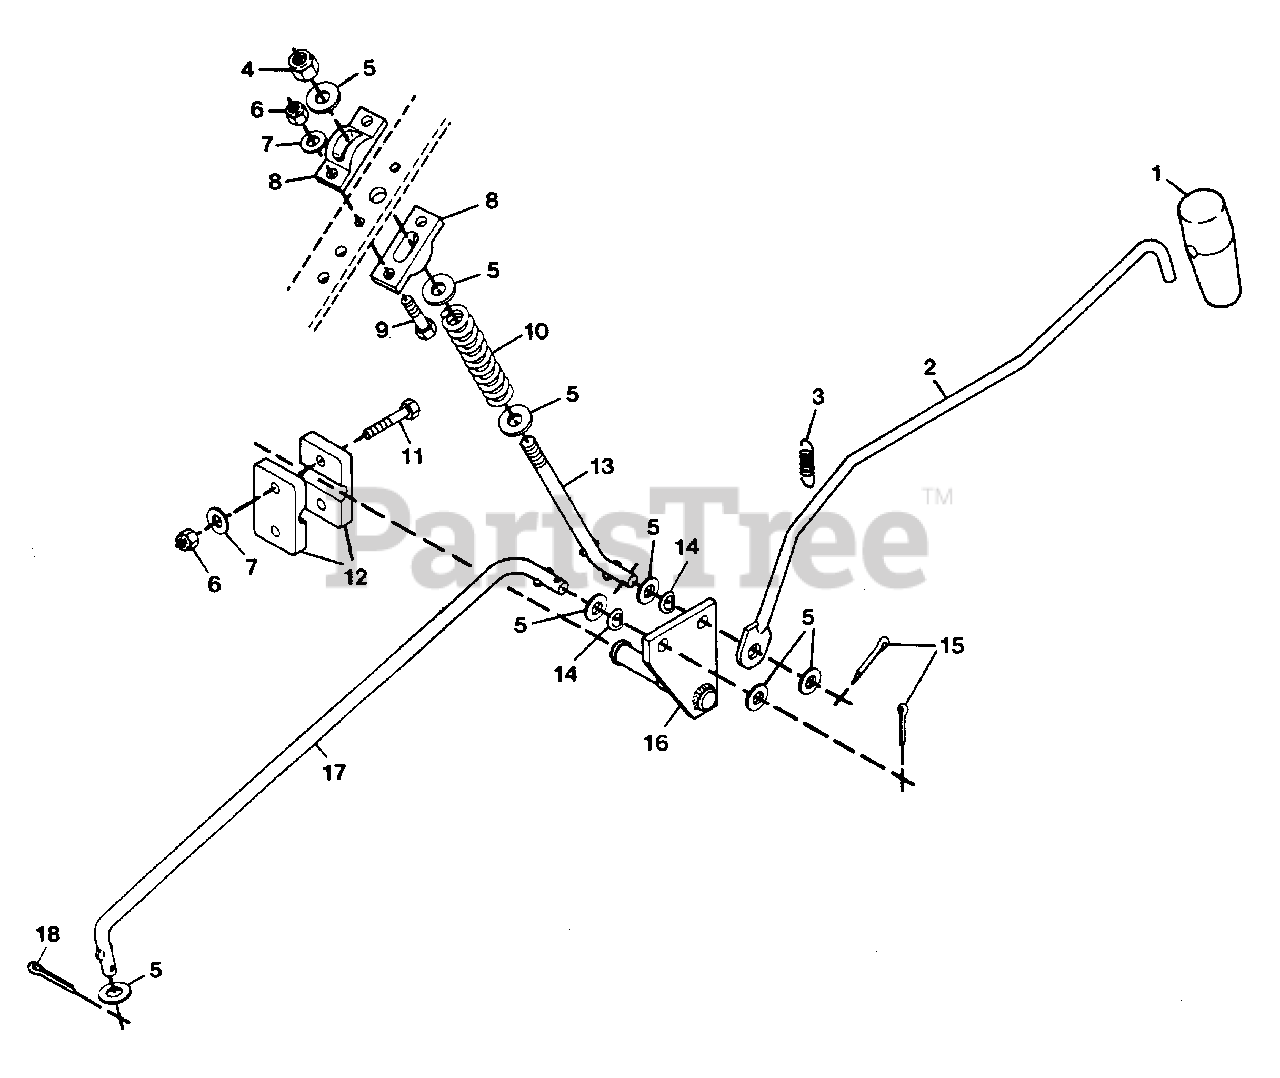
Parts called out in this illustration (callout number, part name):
1	NUT, HEX 3/4-10 LIGHT THIN
2	WASHER, FLAT .812X1.469X.134
3	SPACER
4	SCREW, SET 7/16-14X1.00 SQHCP
5	HUB, WHEEL
6	SPACER
7	BOLT, HEX 3/8-16X.750
8	PLATE, END
9	BEARING, BALL 1.000X2.000X.562
10	RING, RETAINING 2.000 BORE
11	BOLT, STATIONARY CLUTCH
12	PIVOT, STATIONARY
13	PIN, CLUTCH SLIDING
14	O-RING, .438X.625X.094
15	BOLT, HEX 1/2-13X1
16	WASHER, LOCK 1/2 REG.
17	WASHER, OIL STRAINER NUT
18	HOUSING, AXLE 2-SPEED
19	NUT, LOCK 5/16-18
20	WASHER, FLAT .344X.688X.065
21	BUSHING, NYLON .375X.503X.875
22	NUT, LOCK 1/4-20
23	WASHER, FLAT .281X.625X.065
24	WASHER, FLAT .406X.812X.065
25	WELDMENT, ARM SHIFTER
26	SPRING, COMPRESSION 2X.72X15.5
27	NUT, JAM 3/8-24 HEX
28	SPRING, EXTENSION 2.50X.62
29	BUSHING
30	BOLT, 1/4-20X2.25 GR. 8 PHD
31	BRACKET, SPRING 2-SPEED
32	YOKE, SHIFTING
33	AXLE, STRAIGHT DIFFERENTIAL LOCK
34	SEAL, OIL 1.188X2.000X.250
35	CLUTCH, SLIDING DIFFERENTIAL LOCK
36	GASKET, AXLE HOUSING
37	SHIM, AXLE HOUSING .020
38	SHIM, AXLE HOUSING .005
39	CUP, ROLLER BEARING
40	CONE, ROLLER BEARING
41	SHIM, CLUTCH WORM GEAR .020
42	SHIM, CLUTCH WORM GEAR .005
43	NUT, HEX 5/16-24
44	WASHER, LOCK 5/16 INT. TOOTH
45	HOUSING, DIFFERENTIAL LOCK
46	GEAR, DIFFERENTIAL BEVEL
47	GEAR, SPIDER BEVEL
48	BLOCK, DRIVE
49	KEY, WOODRUFF .125X.375 HARD
50	PIN, SPIDER PINION
51	GEAR, 4 LEAD WORM
51	GEAR, 6 LEAD WORM
52	BOLT, HEX 5/16-24X2.75
53	CUP, ROLLER BEARING
54	HOUSING, DIFFERENTIAL
55	CONE, ROLLER BEARING
56	ASSEMBLY, DIFFERENTIAL HOUSING
57	AXLE, STRAIGHT
58	HOUSING, AXLE
59	BOLT, HEX 1/2-13X1 NYLON INSERT
60	SEAL, OIL DRAIN
NS	CONE, ROLLER BEARING
NS	WELDMENT, 6-LEAD WORM
NS	WELDED WORM SHAFT ASM- 6 LEAD
NS	WELDMENT, 4-LEAD WORM
NS	WELDED WORM SHAFT ASM- 4 LEAD
NS	DECAL, MODEL 5200
NS	DECAL, DIFFERENTIAL LOCK
